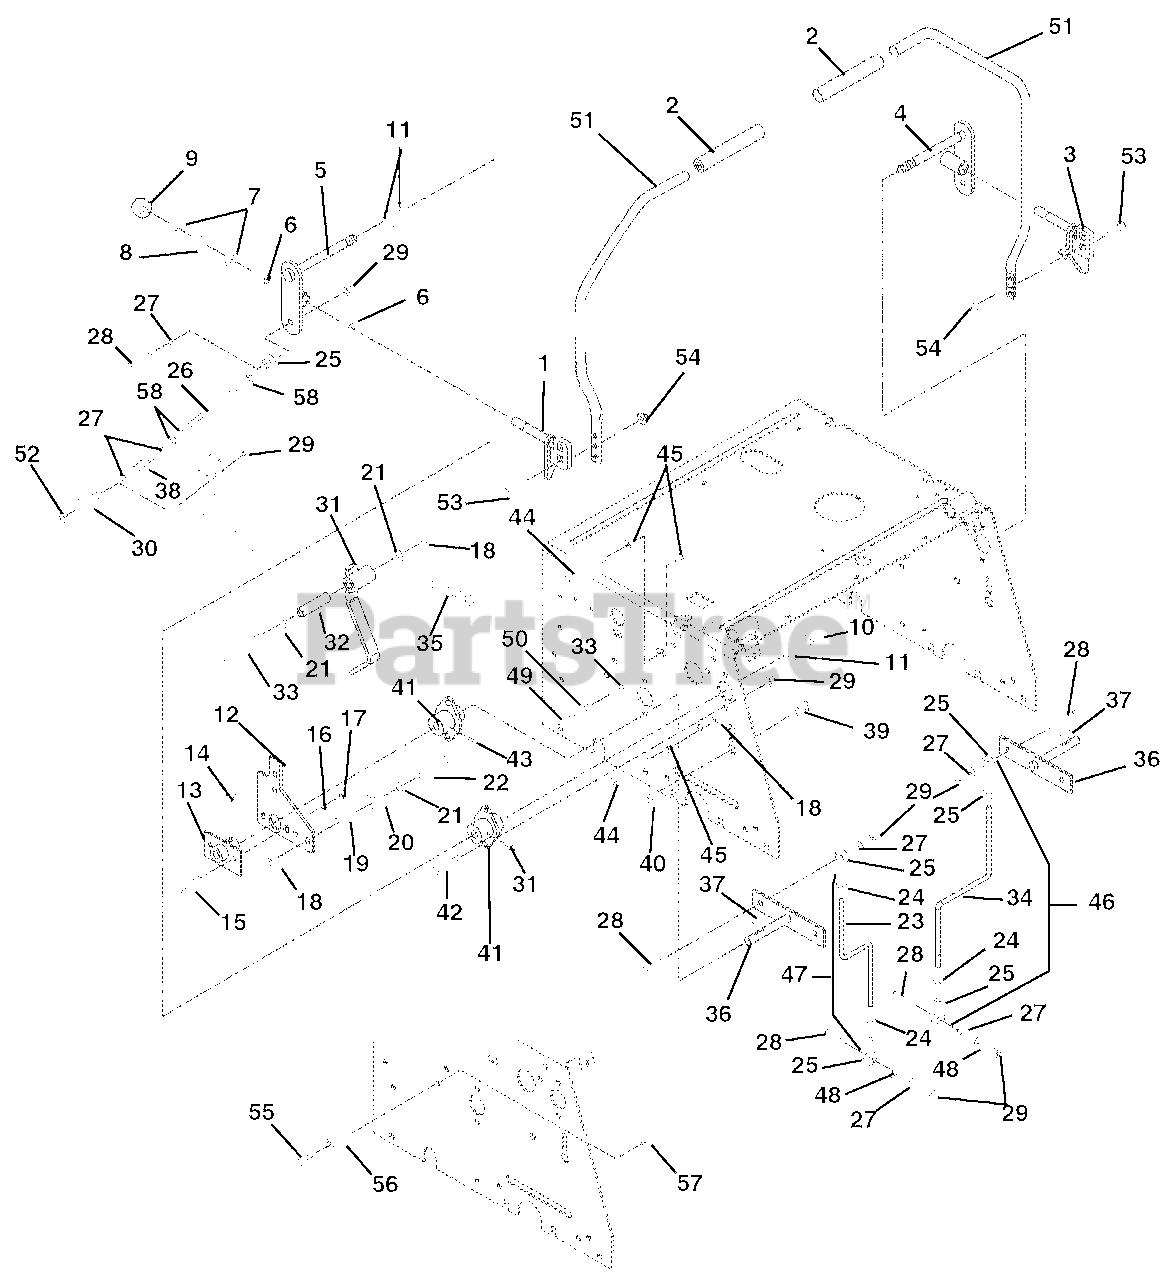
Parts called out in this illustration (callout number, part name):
1	Weldment-Lever Right Hand
2	Grip-Handlebar
3	Weldment-Lever Left Hand
4	Weldment-Rod Left Hand
5	Weldment-Tube Right Hand
6	Bushing-Nylon .5 x .625 x .5
7	Washer-Plastic .12 x .53 x 1.12
8	Spring-Compression
9	Nut-Locking Cone .50-13
10	Nut-Locking-Center .50-20
11	Washer-Flat, Steel .563 x 1.375 x .109
12	Arm-Speed Control
13	Arm-Speed Control
14	Bolt-Hex .25-20 x .50 Grade 5
15	Bolt-Hex .25-20 x .75 Grade 5
16	Washer-Flat Steel .281 x .620 x .065
17	Nut-Locking-Center .250-20
18	Nut-Locking-Center .375-16
19	Hub-Bearing Mount
20	Bearing-Ball .500 x 1.375 x .437
21	Washer-Flat, Steel .406 x .812 x .065
22	Bolt-Hex .38-16 x 2.00 Grade 5
23	Rod-Transaxle Right Hand
24	Nut-Jam .31-24
25	Rod-End-Female .312
27	Washer-Flat-Steel .344 x .688 x .065
28	Bolt-Hex .31-18 x 1.00 Grade 5
29	Nut-Locking-Center .312-18
30	Rod-Pivot
31	Weldment-Neutral Detent
32	Bushing-Sleeve .385 x .610 x 1.80
33	Bolt-Hex .38-16 x 2.75 Grade 5
34	Rod-Transaxle Left Hand
35	Spring, Tension .085 x .60 x 5.13
36	Weldment-Pump
37	Key-Woodruff .13 x .75
39	Switch-Neutral Start
40	Nut-Stamped .56-18
41	Bushing-Flanged
42	Bolt-Hex .31-18 x .75 Grade 5
43	Fitting-Lube .25-28 x .256
44	Bolt-Hex .38-16 x 3.00
45	Nut-Hex .375-16 Grade 2
46	Rod Assembly-Transaxle Right Hand
47	Rod Assembly-Transaxle Left Hand
48	Washer-Flat-Steel .347 x 1.254 x .048
49	Bolt-Hex .31-18 x .75
50	Nut-Hex .31-18
51	Handlebar-Large Frame
52	Washer-Flat-Steel .38 x 87 x .179
53	Bolt-Round Head Square Neck .31-18 x .88 Grade 5
54	Nut-Locking-Top-Flange .31-18
55	Bolt-Hex .31-18 x 2.75 Grade 5
56	Eccentric
57	Nut-Locking-Nylon .31-18
58	Nut-Hex .31-24
